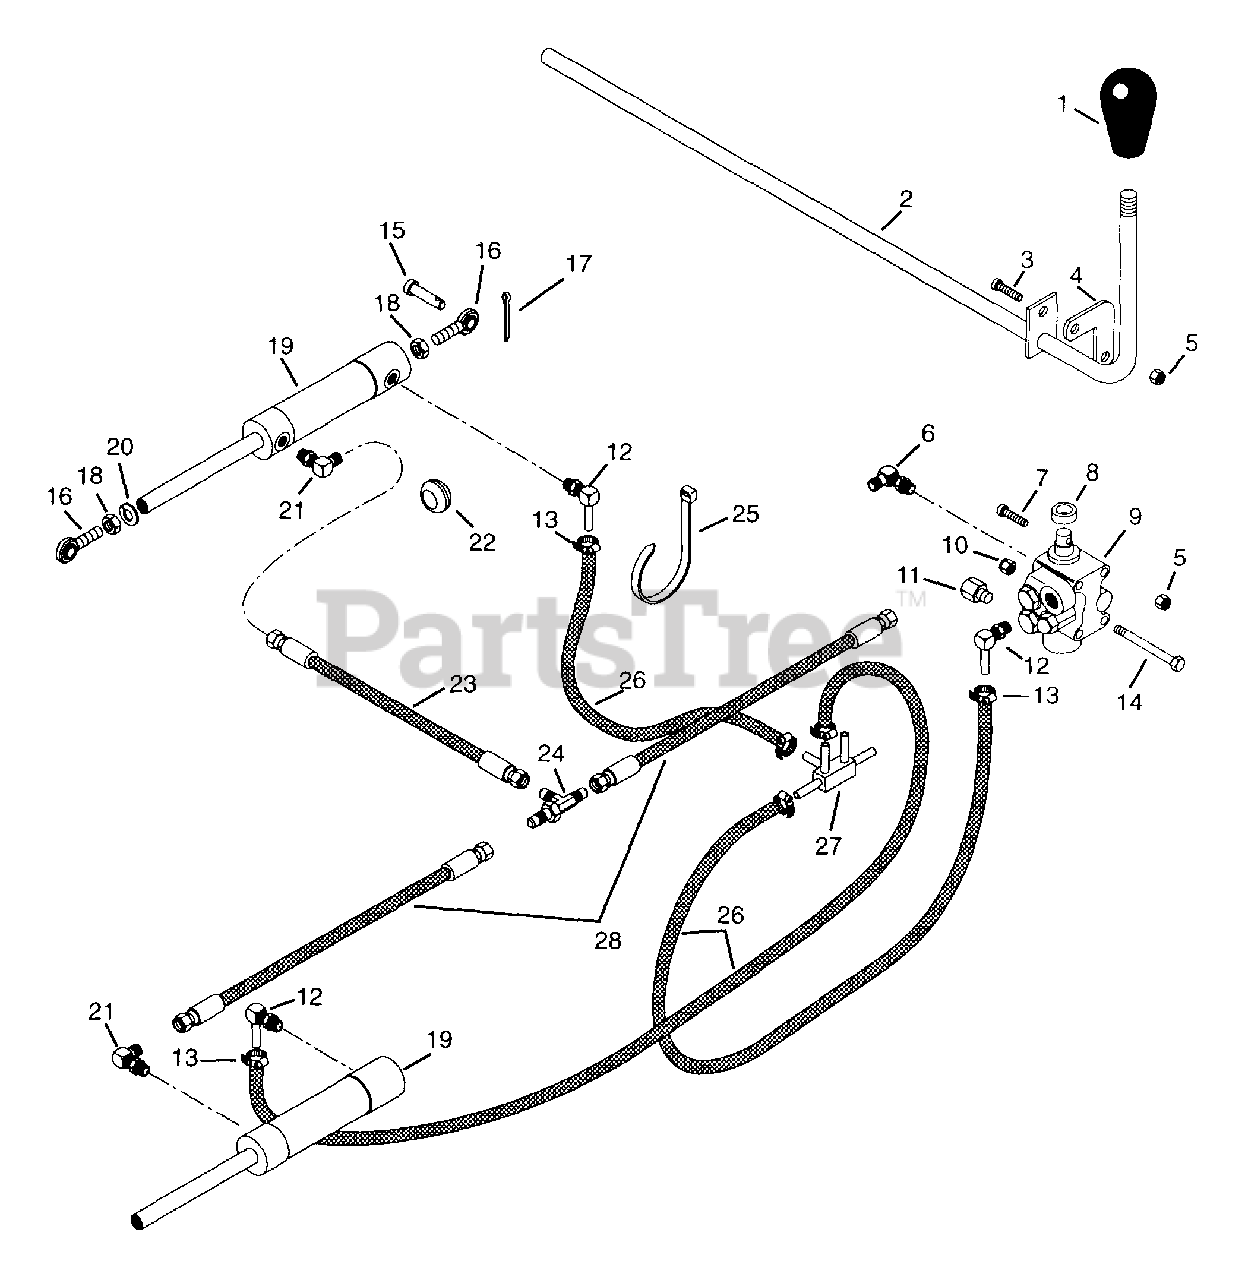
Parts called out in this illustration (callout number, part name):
1	Knob, PTO
2	Weldment, Lift Lever
3	Screw-Machine 10-24 x .625
4	Lift Link
5	Nut-Locking 10-24
6	Adapter
7	Screw-Machine 10-24 x 1.00
8	Spacer .700 x 1.00 x .31
9	Valve, Hydraulic
10	Nut-Locking-Nylon .250-20 Grade 2
11	Plug .44-20
12	Fitting-Adapter .562-18
13	Hose Clamp
14	Bolt-Hex .25-20 x 2.75
15	Pin-Clevis .50 x 1.330
16	Assembly, Rod End (Right Hand)
17	Pin-Cotter .12 x 1.25
18	Nut-Jam .50-20 Grade 2
19	Cylinder, Lift
20	Washer-Lock .50 Reg.
21	Adapter
22	Grommet, 1.25
23	Assembly, Hydraulic Hose
24	Adapter-Bulkhead Tee .56-18
25	Tie Wrap, Black
26	Hose, Hydraulic
27	Fitting-Manifold .38 x 1.50
28	Assembly, Hydraulic Hose
